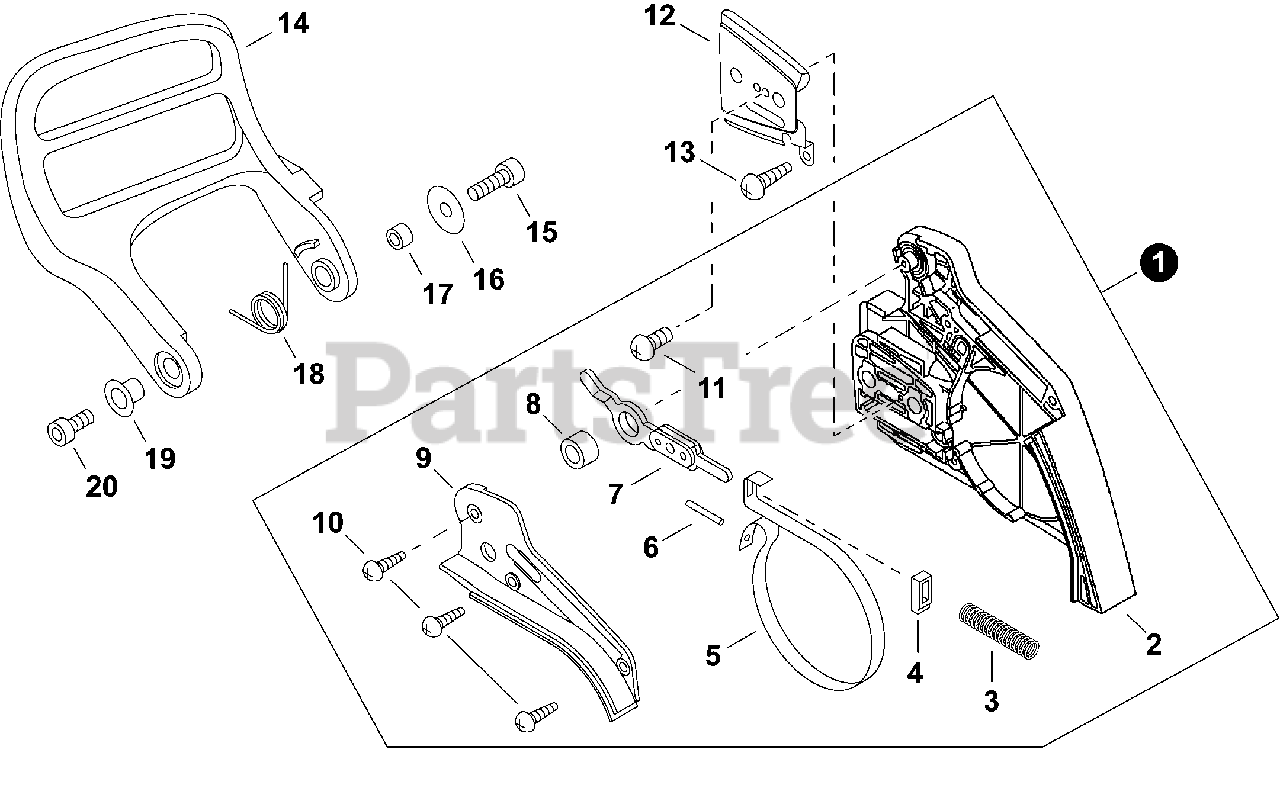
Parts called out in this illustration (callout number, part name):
1	BRAKE ASSY, CHAIN
2	GUARD, SPROCKET
3	SPRING, COMPRESSION
5	BAND, BRAKE
6	PIN, SPRING 3x-9.8
7	CONNECTOR, BRAKE
8	SPACER 8×12×9
9	COVER, BRAKE
10	SCREW 4×12
11	SCREW 3×5
12	PLATE, GUIDE - OUTER
13	SCREW 4×12
14	LEVER, BRAKE
16	WASHER 4.2×16.5×1
17	SPACER 8×12×9
18	SPRING, TORSION
19	COLLAR 10
20	SCREW TAPPING 5×16
